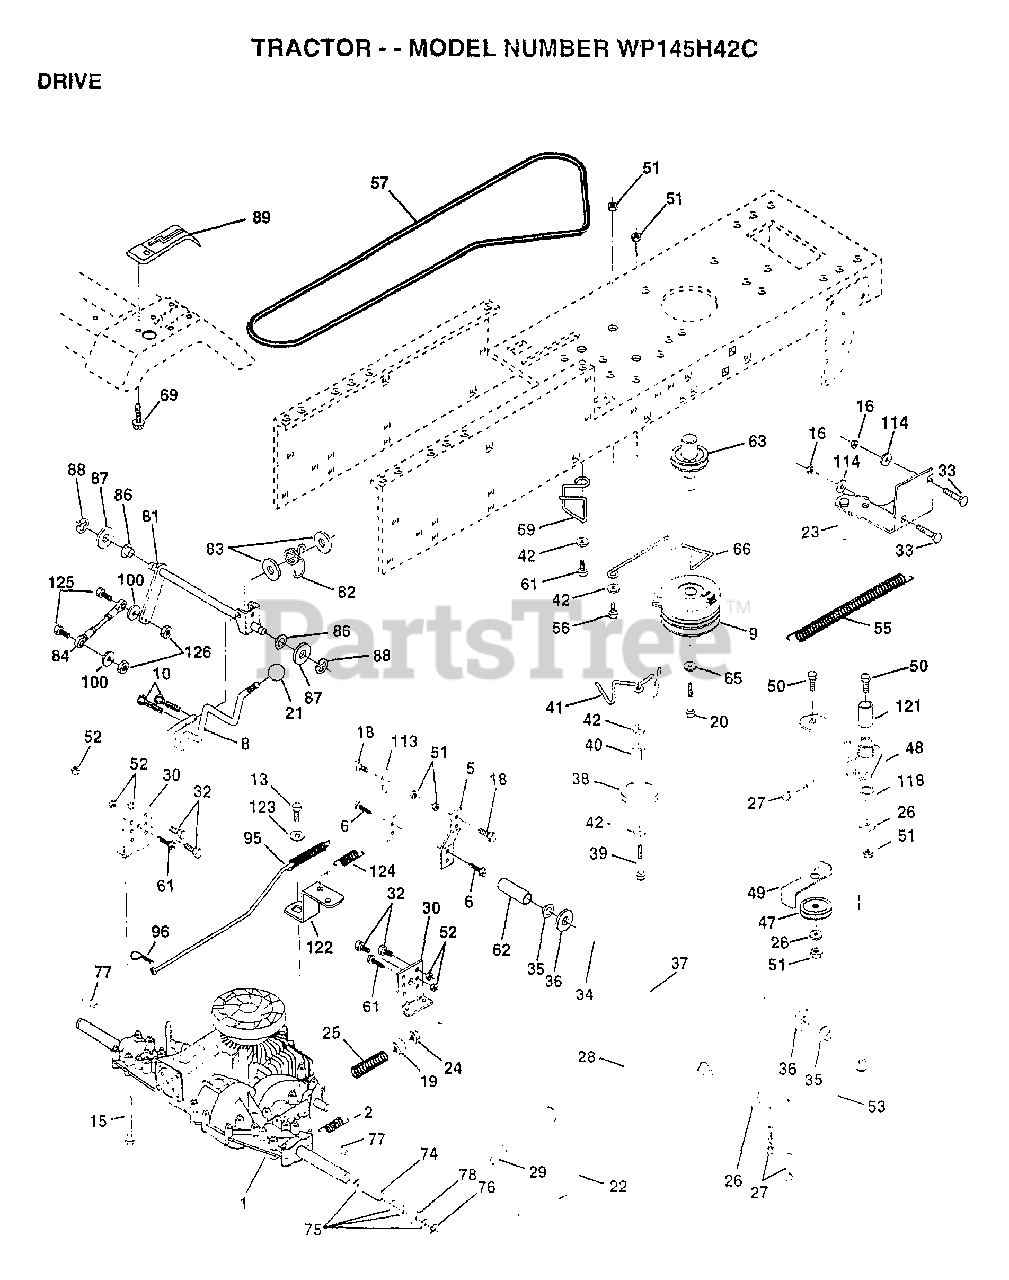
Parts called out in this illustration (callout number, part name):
1	TRANSAXLE, PEERLESS
2	SPRING.BRAKE.RETU
5	STRAP TORQUE
6	SCREW
8	ROD SHIFT FEND YT
9	CLUTCH.ELECT.EVX.
10	PIN COTTER 1/8
13	BOLT.1/4-28.W/PAT
15	BOLT.HX.FLG.5/16
16	NUT
18	BOLT
19	NUT
20	BOLT.7/16-20X4.25
21	KNOB T (1/2-HOLE)
22	BRAKE ROD
23	BRACKET.CLUT.MTG.
24	NUT
25	SPRING ROD LT
26	WASHER
27	COTTER PIN
28	ROD.BRAKE.PARK.LT
29	PLUNGER CAP T
30	TRANSAXLE MTG BKT
32	BOLT
33	BOLT
34	SHAFT ASM-PEDAL F
35	NYLON BEARING
36	WASHER LT
38	PULLEY.IDLER.FLAT
39	BOLT
40	SPACER T
42	WASHER
48	BELLCRANK ASM
49	RETAIN BELT
53	"LINK, CLUTCH T"
55	"SPRING, RETURN LT"
57	"V-BELT,GRD DRIVE"
59	KEEPER BELT CNTSP
61	SCREW
62	PEDAL COVER T
63	PULLEY.CLUTCH.EVX
65	LOCKWASHER
66	KEEPER-BELT
69	SCREW HEXWSH H-L
74	"SPACER AXLE,PVST"
75	WASHER
76	E-RING LT
77	SQUARE KEY
78	WASHER
81	SHAFT ASM CROSS
82	"SPRING,TORSION"
83	WASHER
84	"ROD TIE, PVST 20"""
86	BUSHING
87	WASHER D
88	KLIP RING
95	ROAD ASM BYPASS
96	RETAINER M
100	WASHER M
113	"STRAP,TORQUE"
114	WASHER
118	SPACER-BELLCRANK
121	NYLINER-CLUTCHING
122	"PLATE-BYPASS,PVST"
123	WASHER
124	SPRING RETURN
